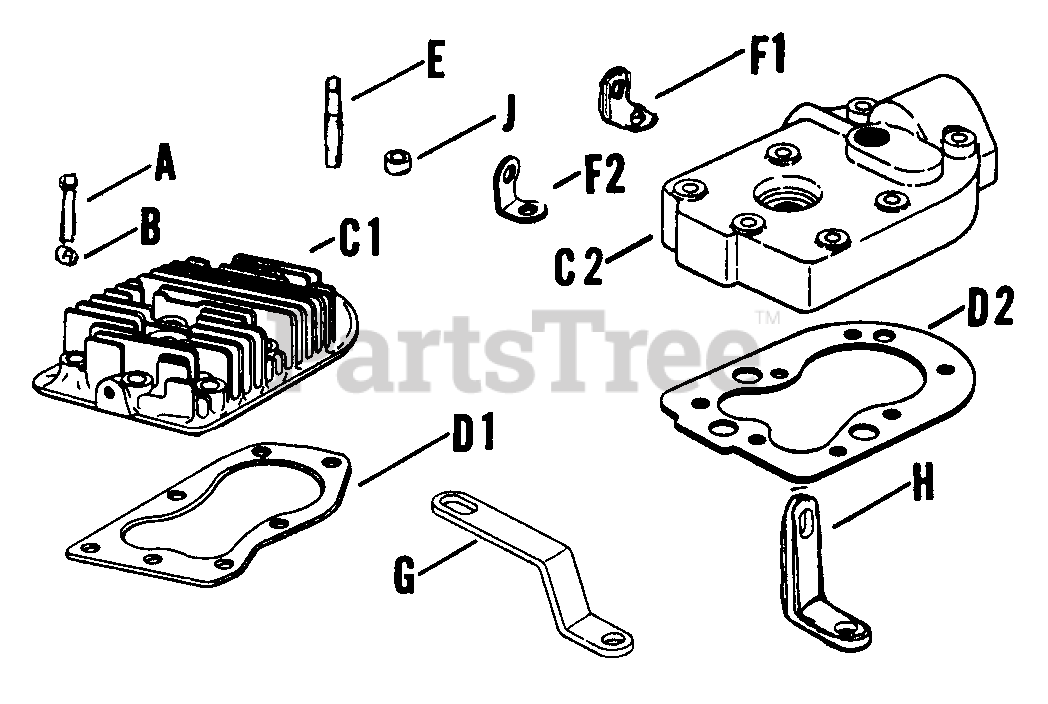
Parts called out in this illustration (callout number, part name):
A	SCREW - USE 41 086 02
B	WASHER, FLAT 5/16"
C1	HEAD - USE 41 015 02
D1	GASKET - USE 41 041 10
